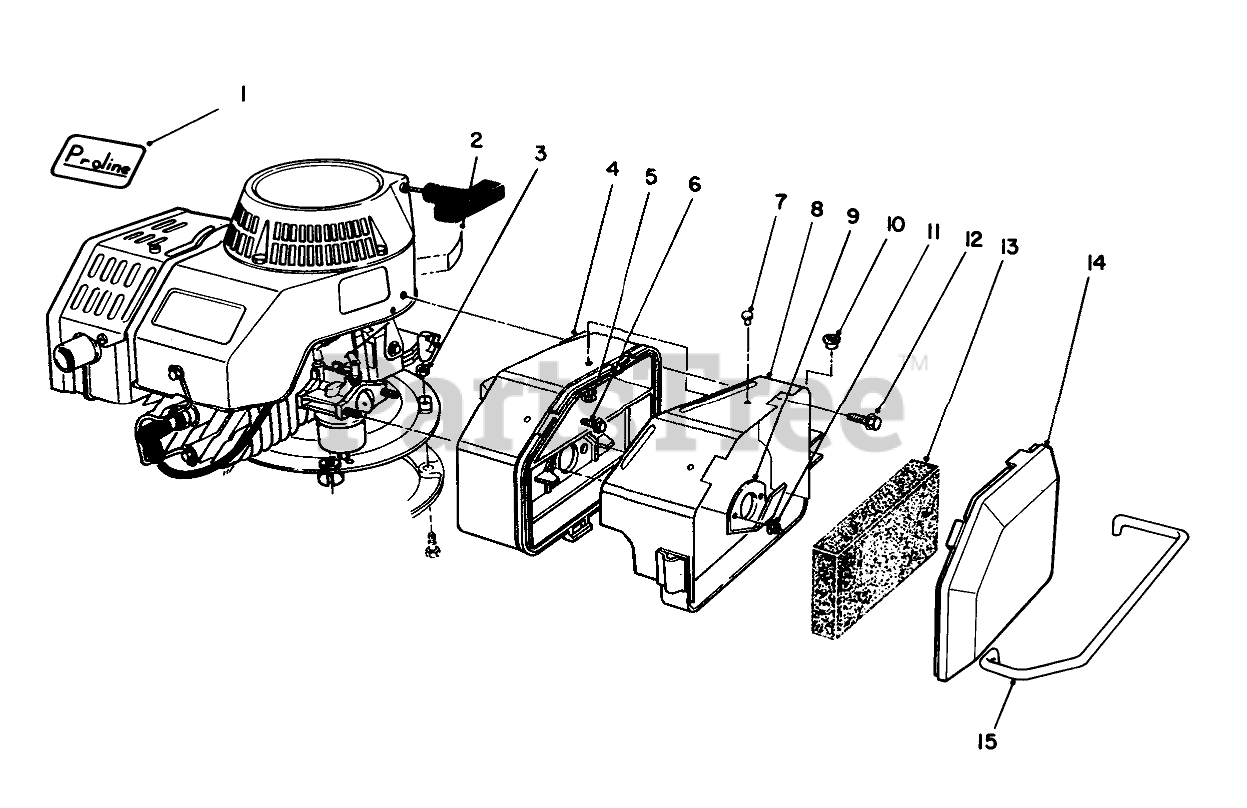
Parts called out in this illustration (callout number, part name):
1	DECAL - PROLINE
2	DECAL - FUEL
3	NUT-JAM
4	Air Cleaner Assembly (Incl. Ref. #5, 7 & 8)
5	WASHER-FLAT
6	HEX FL HD M.6X1.0X25MM
7	RIVET-POP
8	AIR CLEANER COVER WA
9	SPIT BACK DEFLECTOR
10	5/16 ID BSHG
11	NUT-LOCK
12	SCREW-HHF
13	FILTER
14	AIR CLEANER COVER
15	AIR CLEANER GUARD
